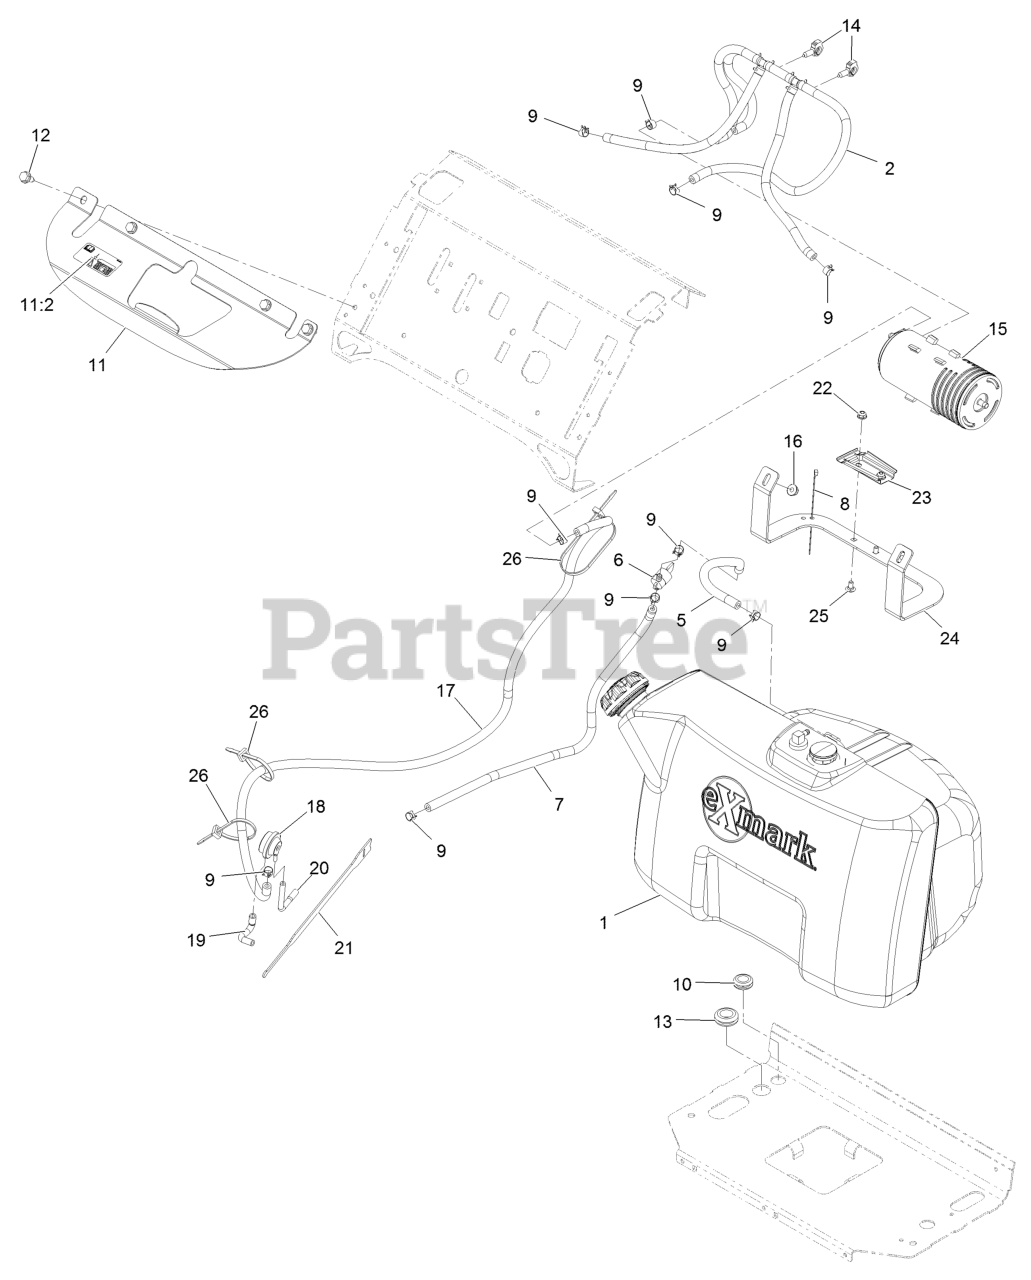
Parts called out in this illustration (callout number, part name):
2	VENT ASM
5	HOSE-FUEL
6	VALVE-FUEL
7	HOSE-FUEL
8	TIE-CABLE
9	CLAMP-HOSE
10	GROMMET
11	BRACKET-TANK
11:2	Decal-Fill, Fuel
12	Screw-HWH 5/16-18 X 3/4 Tf
13	GROMMET
14	CLIP-HARNESS
15	CANISTER-CARBON, 800CC
16	NUT-HF, NI
17	HOSE-FUEL
18	VALVE-CONTROL, VACUUM
19	HOSE-VENT, FORMED
20	HOSE-VENT, FORMED
21	STRAP-VELCRO, CABLE TIE
23	BRACKET-CANISTER, CARBON
24	BRACKET,CANISTER MOUNTING
25	SCREW-CARR
26	TIE-CABLE
